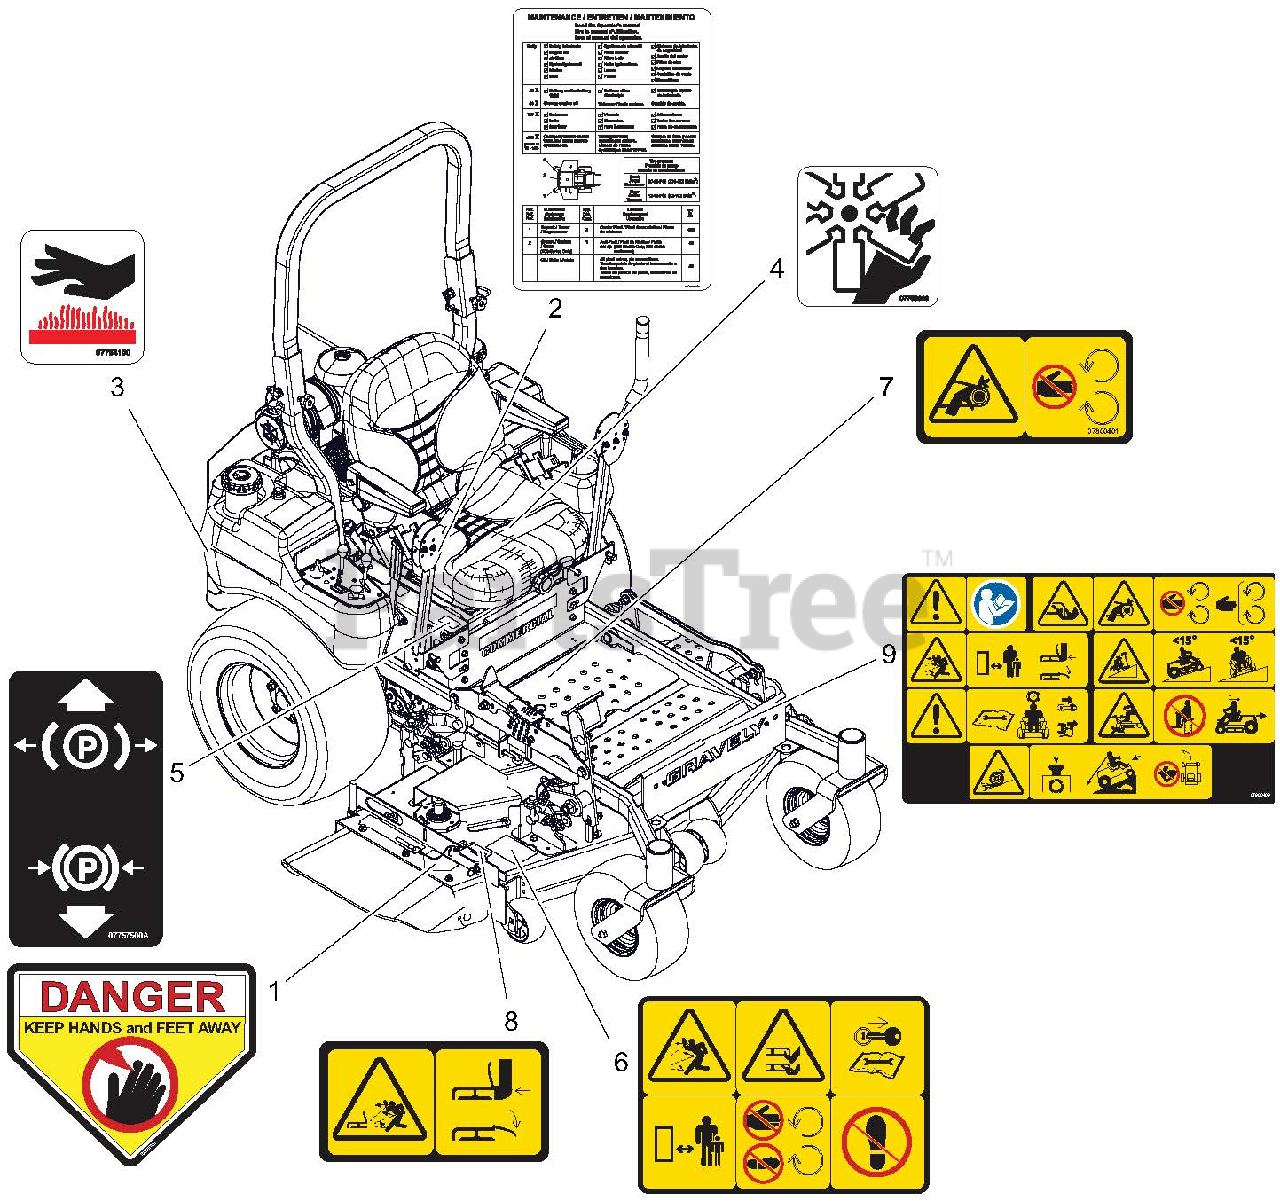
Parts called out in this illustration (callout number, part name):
1	DECAL, DANGER
2	DECAL, MAINT
3	DECAL HOT SURFACE
4	DECAL, DANGER - FAN
5	DECAL, PARKING BREAK LEVER
6	DECAL, SAFETY - MOWER DECK
7	DECAL, SAFETY - GUARDING
8	DECAL, SAFETY - DECK GUARDING
9	DECAL, MAIN SAFETY, COMMERCIAL
